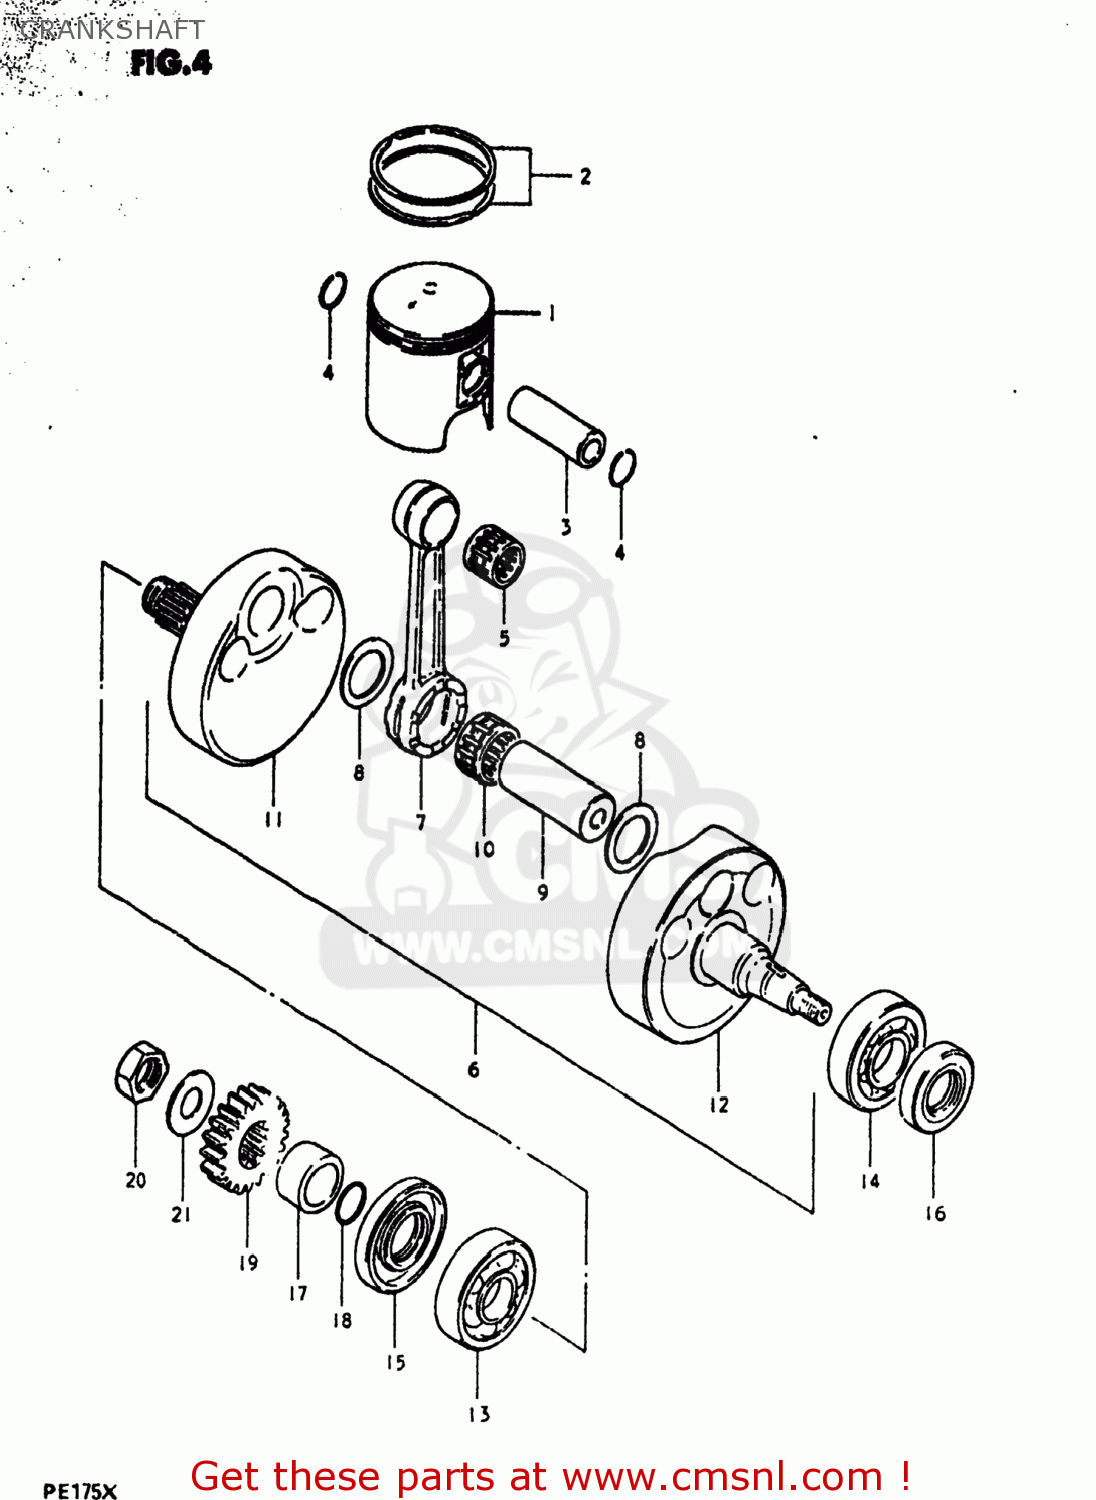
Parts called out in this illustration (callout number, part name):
1	PISTON
2	RING SET,PISTON
3	PIN,PISTON
4	RING,SNAP 16MM
5	BEARING
6	CRANKSHAFT ASSEMBLY
7	ROD,CONNECTING
8	WASHER(22X35X1)
9	PIN,CRANK
10	BEARING
11	CRANKSHAFT
12	CRANKSHAFT,LEFT
13	BEARING
14	BEARING
15	SEAL,OIL(29X47X8)
16	SEAL,OIL(25X44X7)
17	SPACER
18	O RING(D:2.4,ID:19.8)
19	GEAR,PRIMARY DRIVE
20	NUT
21	WASHER
